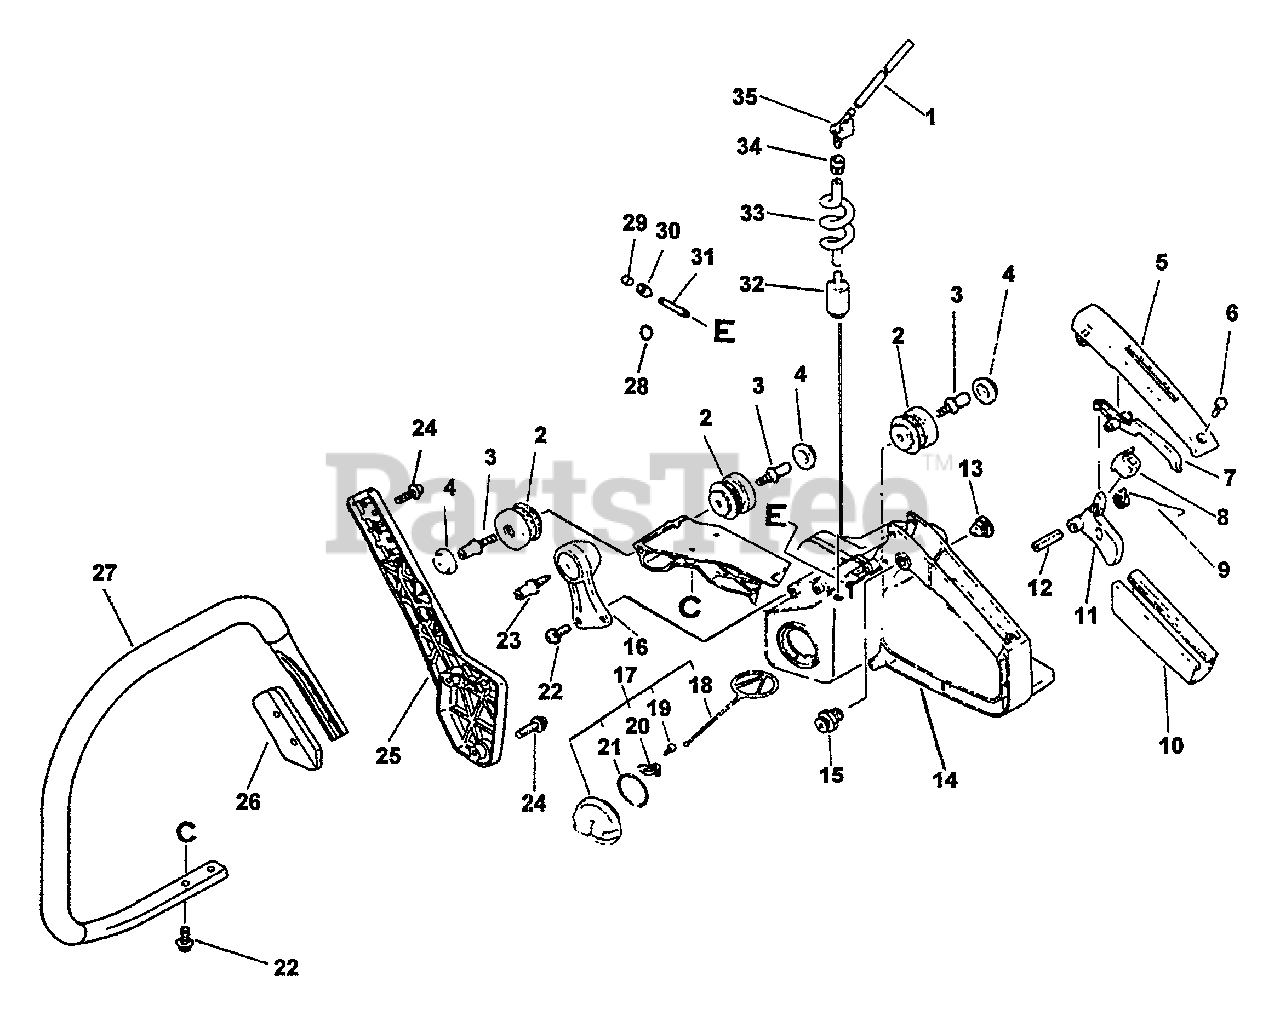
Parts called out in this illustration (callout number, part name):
1	PIPE, FUEL - 3×6×100
4	CAP, CUSHION
5	COVER, HANDLE
6	SCREW 4×14
7	LEVER, THROTTLE LOCKOUT
8	CUSHION, THROTTLE
9	SPRING, THROTTLE RETURN
11	TRIGGER, THROTTLE - ORANGE
12	PIN, SPRING Ø5×25 MM
14	HANDLE - REAR
15	LOCK, THROTTLE TRIGGER
17	CAP ASSY
18	CONNECTOR, CAP L= 60 MM
19	SCREW, TAPPING 3×8
20	RETAINER, CONNECTOR
21	O-RING 29
22	SCREW 5×14
24	SCREW 5×20
25	BRACKET, GRAY HANDLE
26	BRACKET, HANDLE
27	HANDLE, FRONT
29	VENT ASSY
30	HOLDER, VENT
31	PIPE, VENT
32	FILTER, FUEL
33	PIPE, FUEL
34	GROMMET
35	CONNECTOR, PIPE
